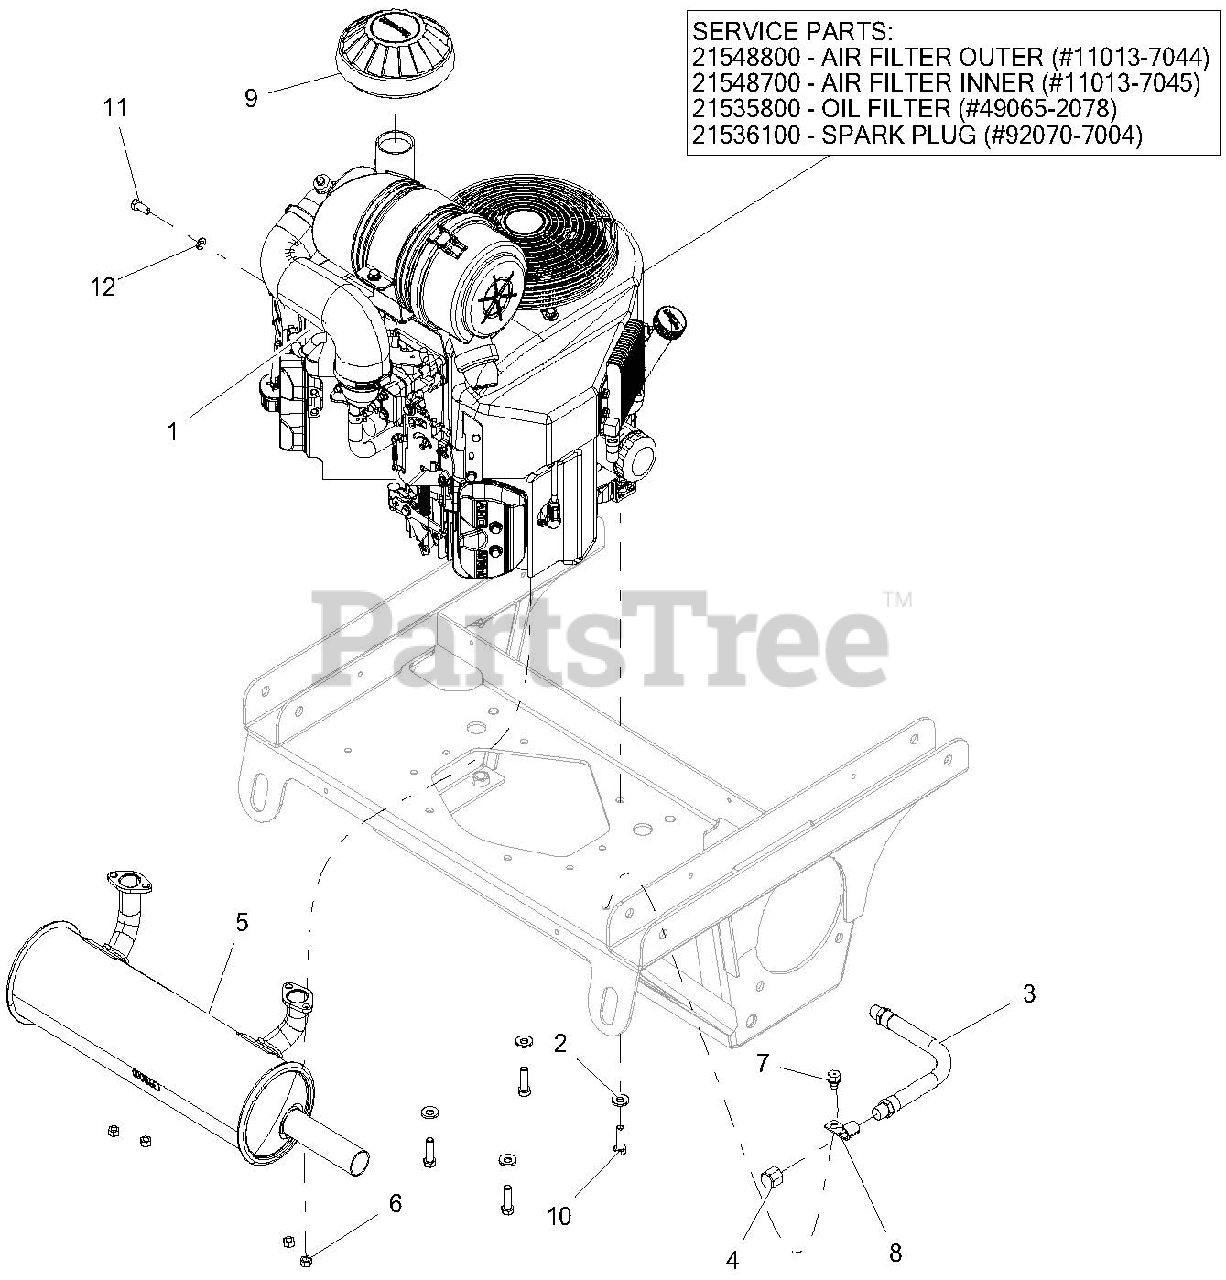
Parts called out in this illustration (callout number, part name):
1	ENGINE, ENVIROGUARD LP CONVERSION
1	AIR FILTER OUTER
1	AIR FILTER INNER
1	OIL FILTER
1	SPARK PLUG
2	WSHR, 3/8" SPRING DISC
3	HOSE, HYD .38-11-0K M6N0-M6NO
4	PIPE, CAP 3/8 NPT FEMALE
5	MUFFLER, 27-31 FX KAW
6	NUT-LK-TOP M8-1.25 YWZC
7	SCR-TAP .38-16X.50 HWH TR YWZ
9	CAP, AIR CLEANER INTAKE
10	BLT-HEX .38-16X1.25 GR5 YWZC NYTORQ
11	@BLT-HEX M8-1.25X20 YWZC
12	WSHR-LK .31X.078 REG YWZC
